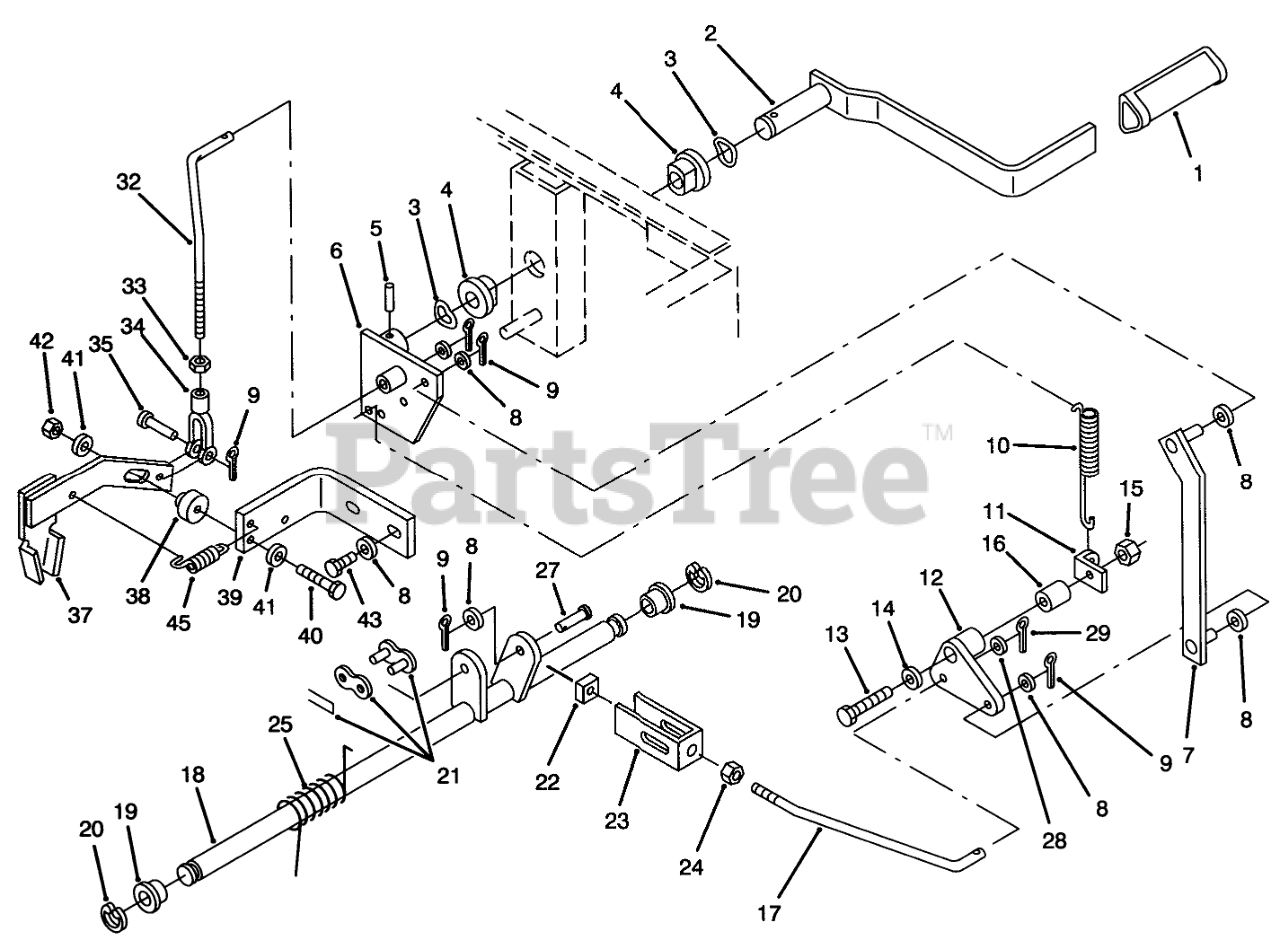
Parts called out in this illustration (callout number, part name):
1	GRIP-PARKING BRAKE
2	Brake Lever
3	WASHER-BOWED
4	BEARING-FLANGED
5	PIN-SPIRAL
6	Arm
7	ASSY-BRAKE BAR UP
8	WASHER-PLAIN
9	PIN-COTTER
10	SPRING-EXTENSION
11	CLIP - SPRING
12	WLMNT-BRAKE PIVOT
13	SCREW-HH
14	WASHER-FLAT
15	NUT-LOCK, NI
16	SPACER
18	Shaft-Brake
19	BUSHING
20	Ring-Snap
21	CONNECTING LINK
22	Nut-Square
23	YOKE-ADJUSTER
24	NUT-HEX
25	SPRING-TORSION
28	WASHER-FLAT
29	PIN-COTTER
32	ROD-NEUTRAL LOCK
33	NUT-JAM
34	CLEVIS
37	Lock-Neutral
38	SPACER
39	Bracket-Support
40	SCREW-HH
41	WASHER-FLAT
42	NUT-LOCK, NI
43	Screw
45	SPRING-EXTENSION
